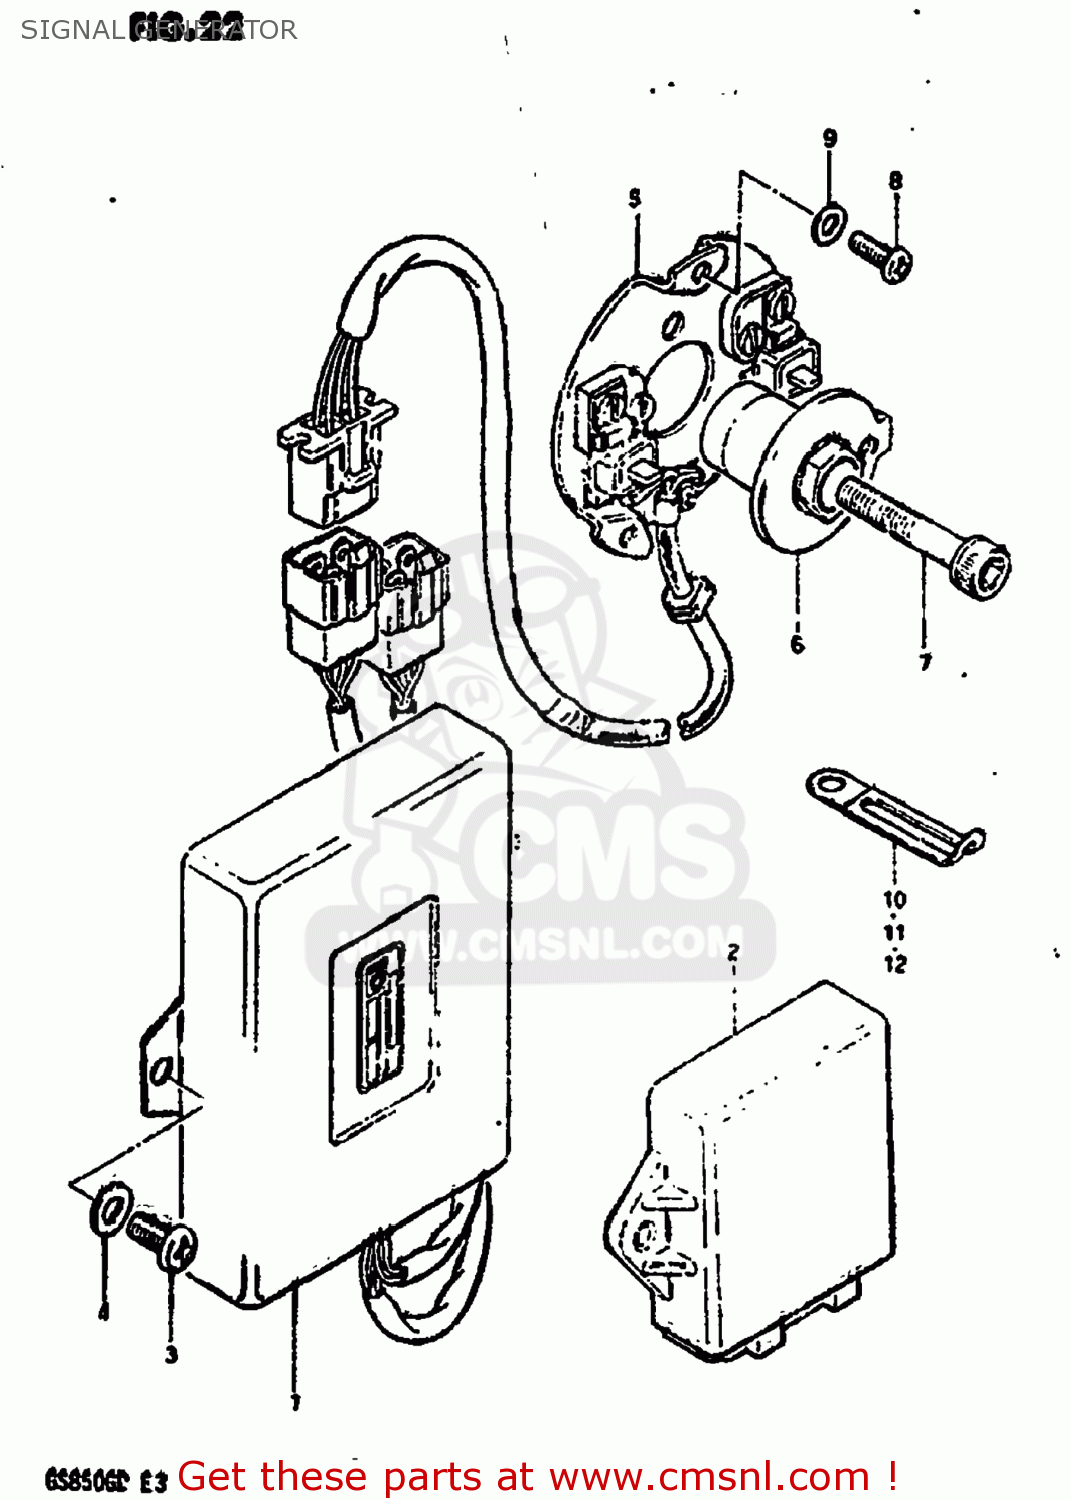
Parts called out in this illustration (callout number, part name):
1	IGNITER UNIT ASSEMBLY
2	IGNITOR UNIT,ESA
3	SCREW 6X12
4	WASHER
5	STATOR,SIGNAL GENERATOR
6	GOVERNOR ASSEMBLY
7	BOLT
8	SCREW(5X12)
9	WASHER
10	CLAMP L:35
11	CLAMP
12	CLAMP
